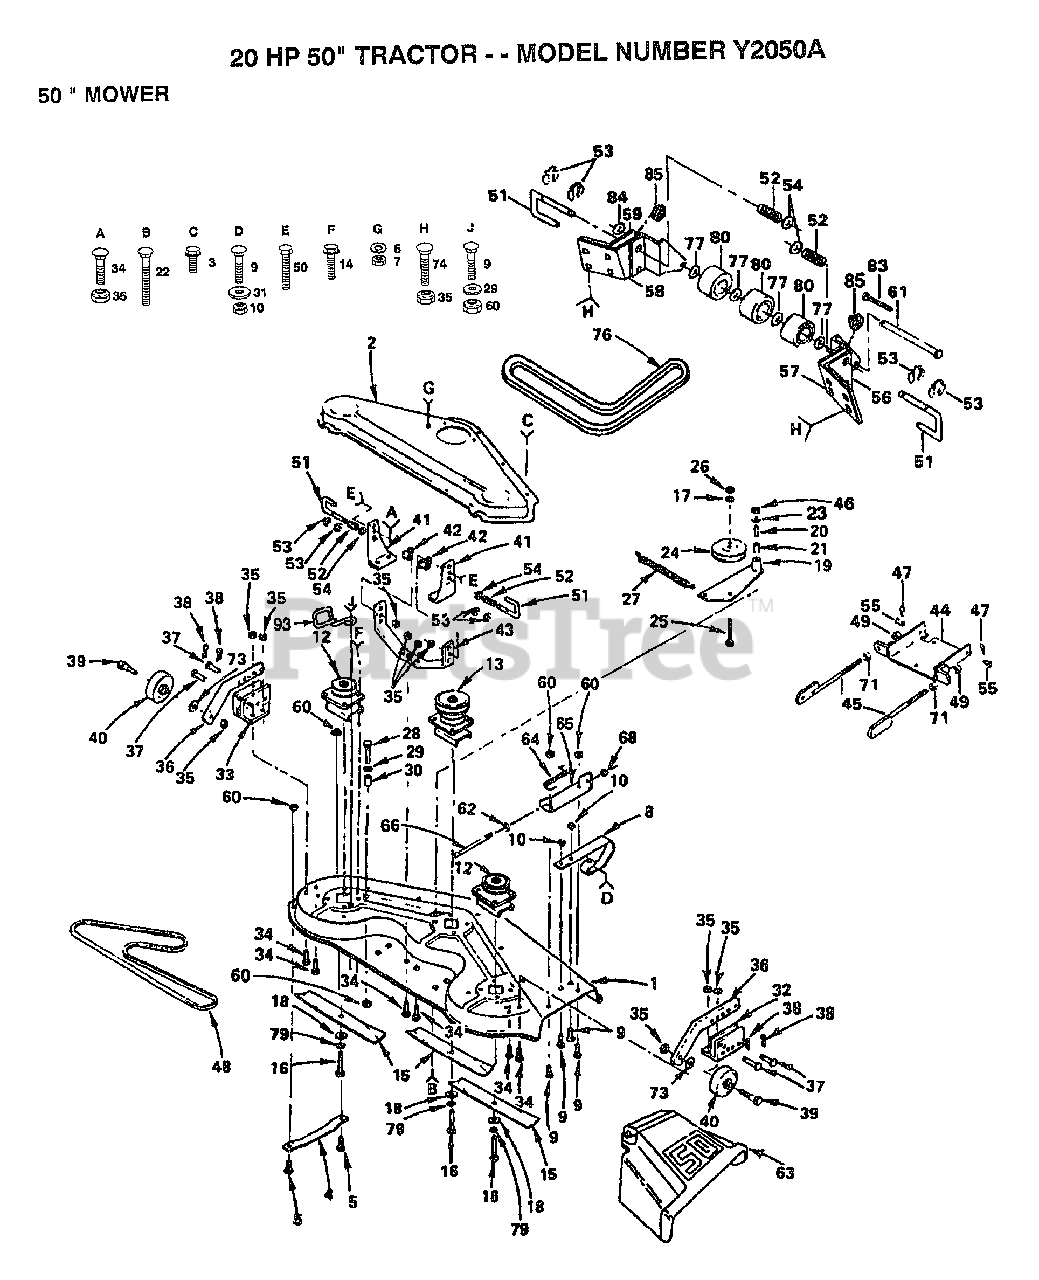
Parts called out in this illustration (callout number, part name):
2	CVR DRIVE DECK
3	SCREW LT
4	RUNNER-LH M
5	BOLT
6	LOCKWASHER
7	NUT.HEX.5/16-18
9	BOLT
13	JACKSHAFT
14	SCREW
15	"BLADE.50""STD.LIFT"
16	BOLT.3/8-24X1-1/2
17	LOCKWASHER
18	WASHER
19	ARM ASSY GT
22	BOLT
24	IDLER-FLAT T
26	NUT.HEX.3/8-16UNC
27	SPRING T
28	BOLT
29	WASHER M
30	SPACER SPLIT LT
31	WASHER
32	GUAGE WHL BRKT GT
33	GUAGE WHL BRKT GT
34	BOLT
36	GUAGE WHL BAR GT
39	BOLT M
40	WHEEL.GAGE.BLK.PL
41	SUSP BRKT GT
42	SPACER GT
43	SUSP BRACE GT
45	BRACKET.SUSPEN.AS
46	JAM NUT TI
47	RETAINER.SPRING
48	V-BELT M
49	NUT LTV
50	BOLT
51	RELEASE PIN GT
52	SPRING M
53	KLIP RING
55	CLEVIS PIN GT
56	BRACKET T
57	BRACKET T
58	BRACKET T
59	BRACKET T
61	PIVOT PIN T
62	WASHER
63	DEFLECTOR
66	ROD-HINGE T
68	NUT PUSH M
71	NUT
73	WASHER
74	BOLT
76	BELT-V.93.5.MWR
77	WASHER T
80	ROLLER T
83	COTTER PIN
85	SPACER T
93	BELT RETIANER
